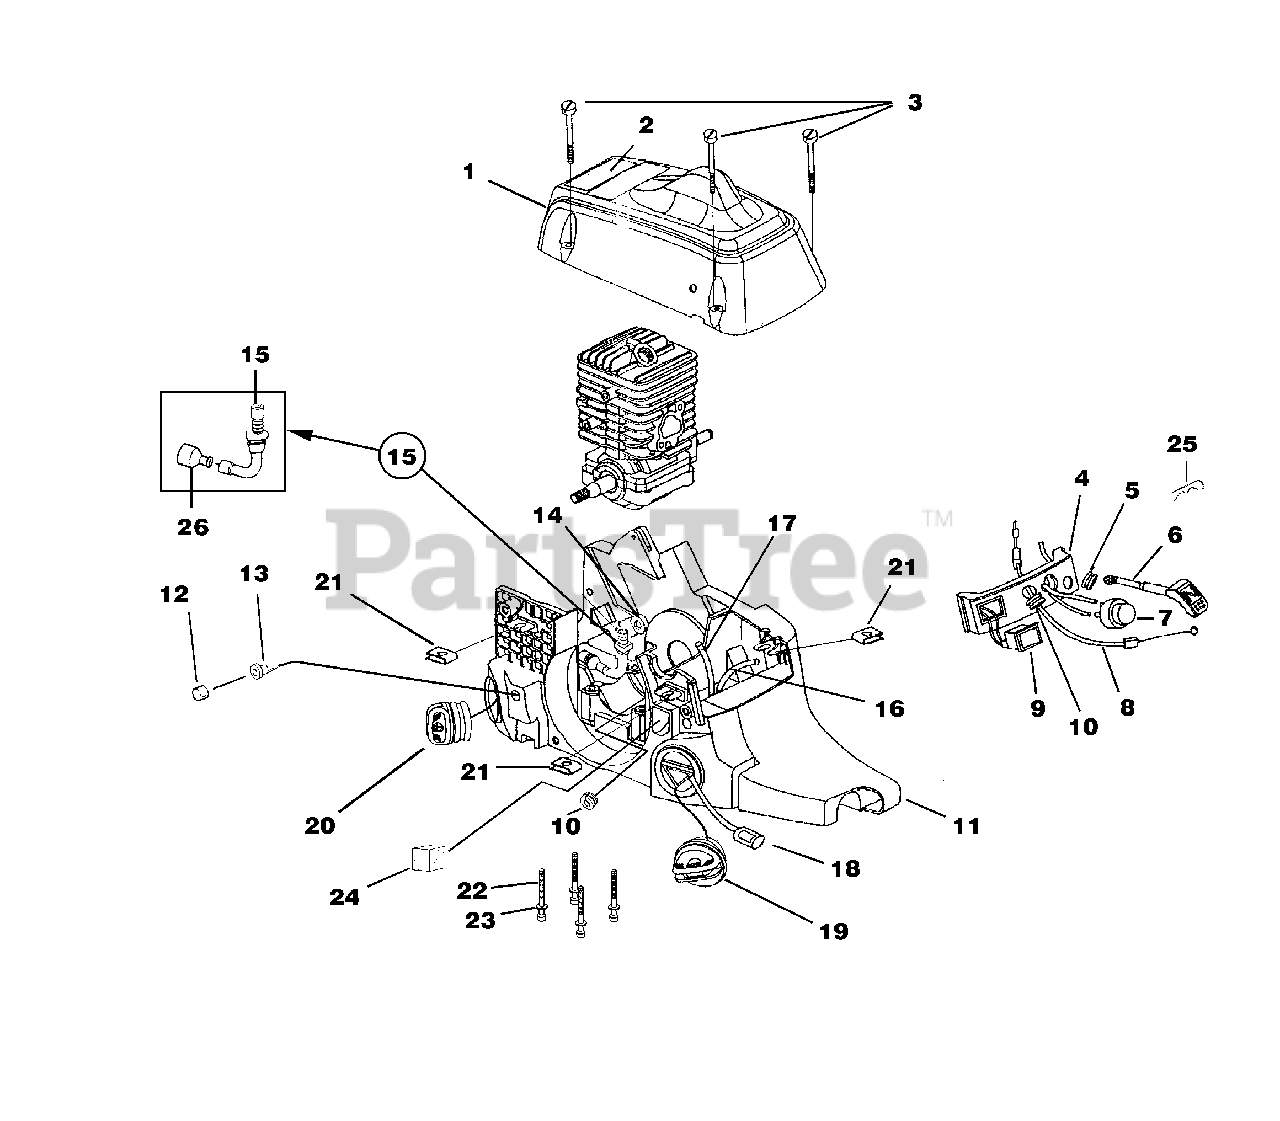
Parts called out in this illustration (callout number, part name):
1	Cylinder Cover Kit
2	Safety Decal
3	Screw-Slotted Pan Hd.
4	Control Panel
5	Grommet
6	Rod, Choke
7	Bulb, Air Purge
8	Throttle Cable
9	Switch, Rocker
10	Grommet - Split
11	Engine Housing
12	Element, Filter (Bronze)
13	Duck Bill Valve
14	Oil Outlet Grommet
15	Oil Intake Tube
16	Rubber Tubing (5 1/2")
17	Rubber Tubing (8 1/2")
18	Fuel Filter
19	Fuel Cap w/ Retainer
20	Oil Cap w/ Retainer
21	Speed Nut ("U-Type")
22	Screw, Cap-Socket Hd. (10-24 x 2")
23	Washer
24	Pre Filter
25	Spring Clip (Choke Rod)
26	Oil Filter
